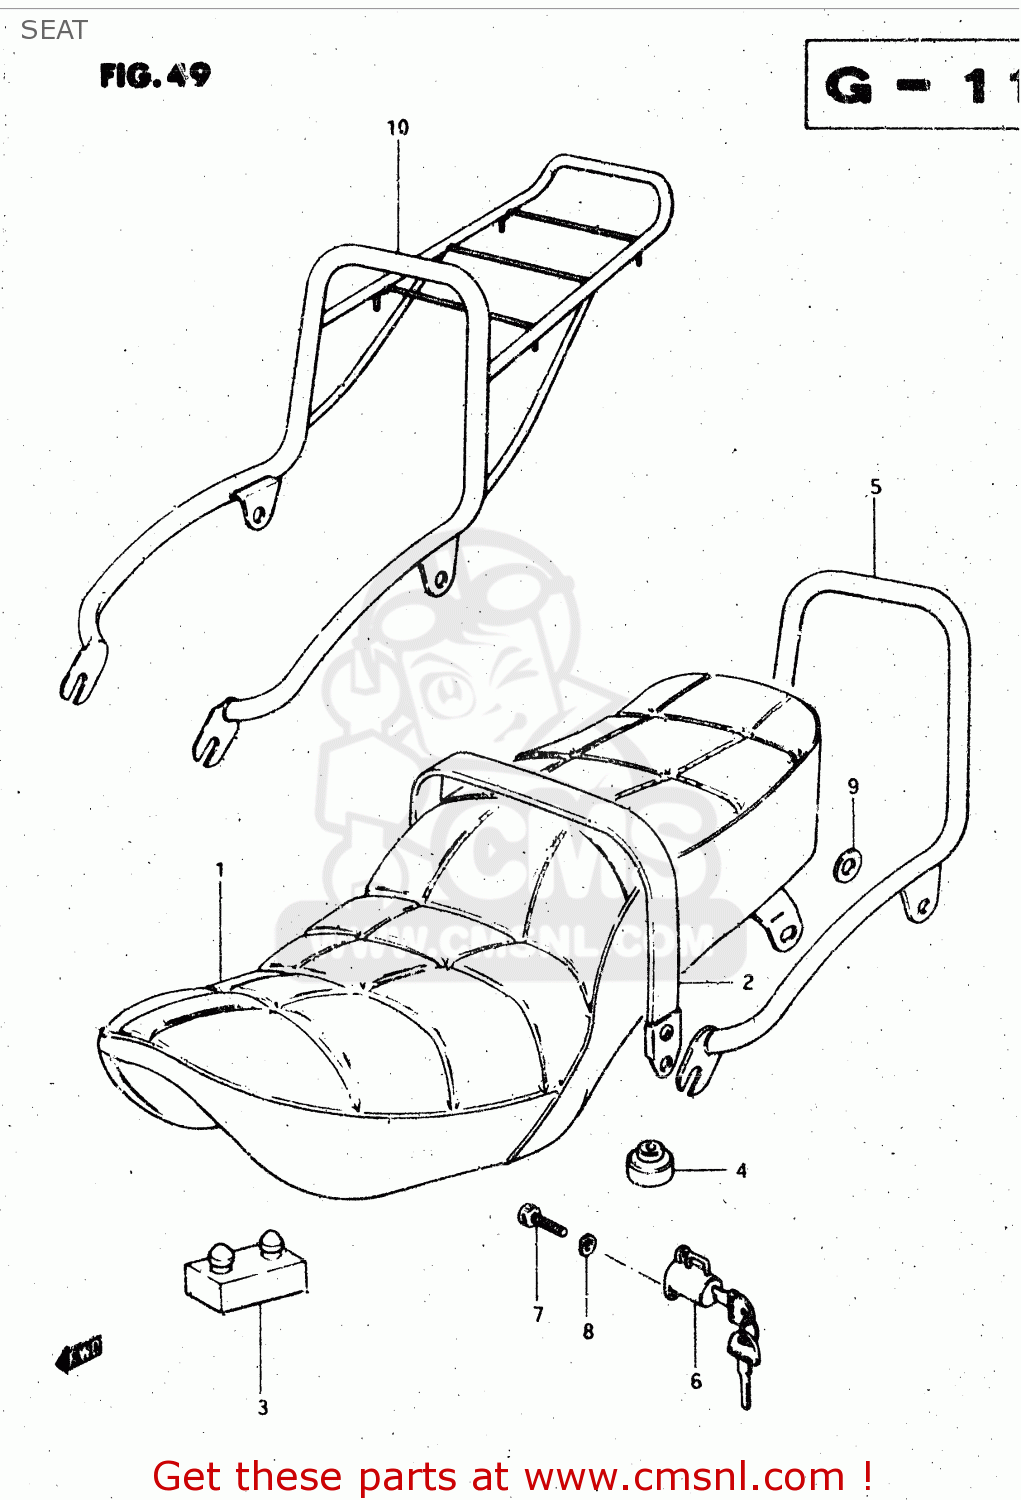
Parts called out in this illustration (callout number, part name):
1	SEAT ASSY (BLACK)
2	BAND, SEAT GRIP
3	CUSHION
4	CUSHION
5	HANDLE,PILLION RIDER
6	LOCK ASSEMBLY,HELMET
7	BOLT 6X11
8	LOCK WASHER
9	WASHER
10	CARRIER, SPORTS
